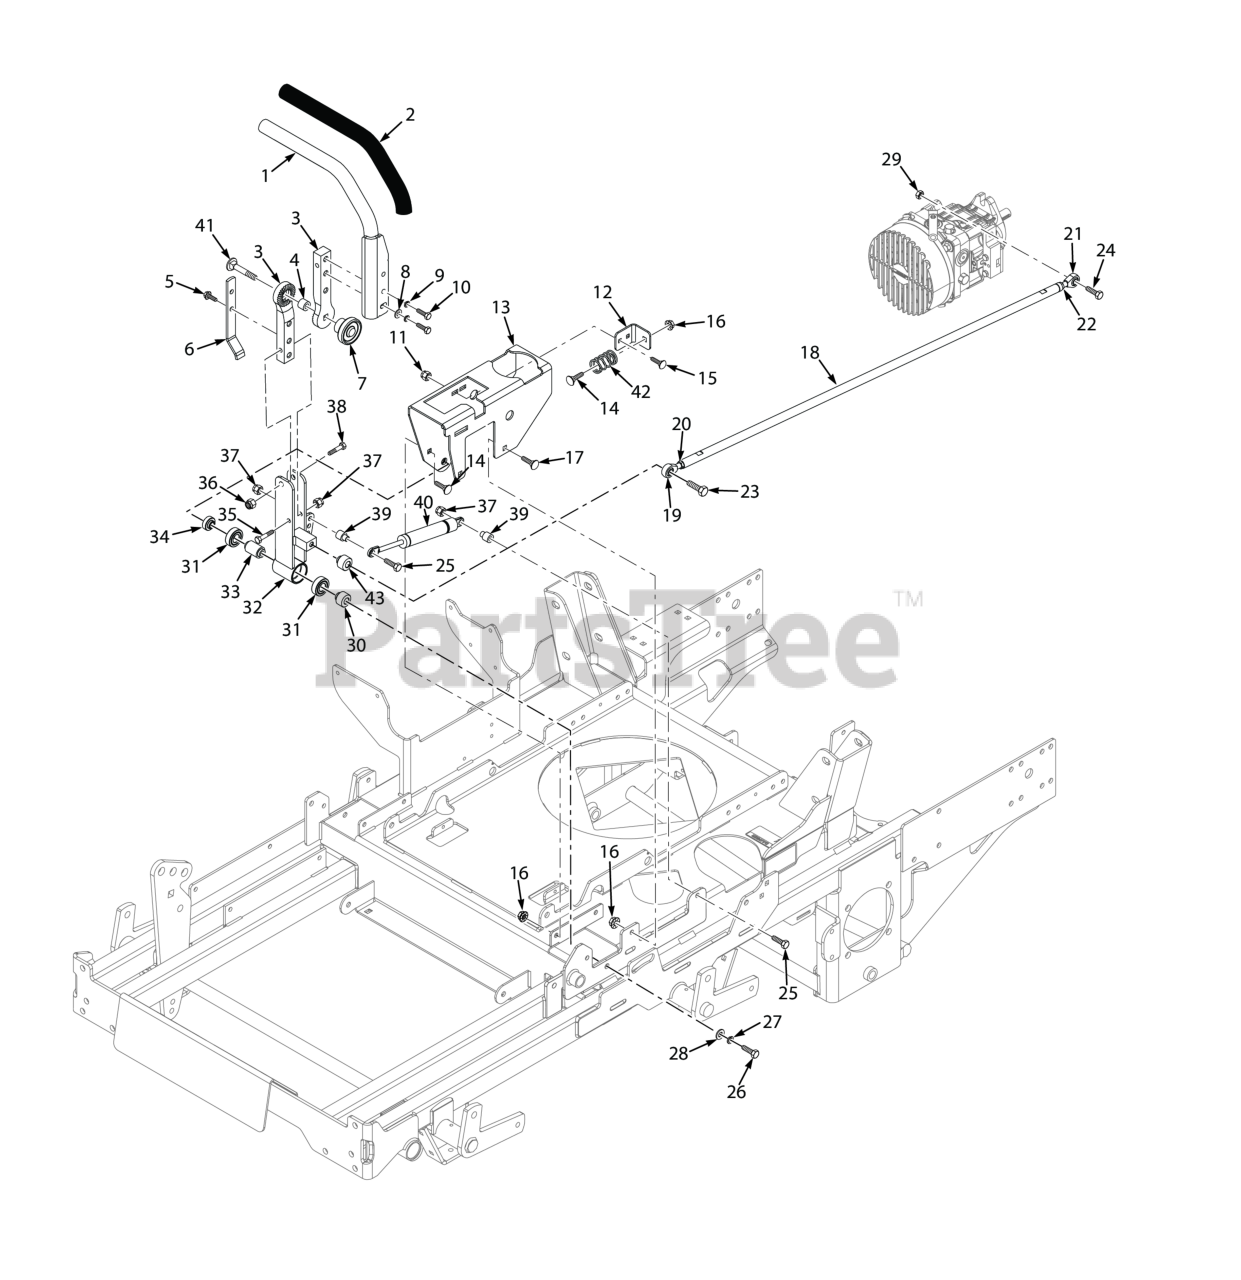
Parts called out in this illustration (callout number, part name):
1	Handle Bar w/Grip - LH
2	Grip, Control Handle
3	ADJUSTMENT ASSY, CNTL HANDLE
4	Spacer, Rubber
5	Capscrew, 5/16-18 x .75 Serrated Flange Hex Head
6	Actuator, Switch
7	Knob, Control Handle
8	Flatwasher, 5/16-.375 x .875 x .083 (35BV & 37BV-EFI)
9	Lockwasher, 5/16 (.317 x .586 x .078) Helical Spring
10	Bolt, Heax Head 5/16-18 x 1" (48V / 52V)
11	Nut, Flanged Elastic Stop 1/4-20
12	Mounting Bracket, Spring Return
13	Control Plate w/Decals LH
14	Bolt, 5/16-18 x .75 RHSN Carriage
15	Serr. Fl. Hex Head CPSCR, 1/4-20 x 3/4"
16	Nut, Serrated Flange 5/16-18 (Right Front Engine Mounting, Briggs and Kohler Only)
17	HHCS, 5/16-18 X .75 FLG
18	Linkage Assy., Pump Control (incl. #19 - #22)
19	Rod End, Male 3/8"-24 LH Thread
20	Nut, 3/8-24 UNF LH Jam
21	Rod End, Male - RH, 3/8-24 Thread
22	Nut, 3/8-24 UNF R.H. Thread
23	Bolt, Hex Head 3/8-16 x 1-3/4" (Kohler EFI)
24	Bolt, Hex Head 3/8-16 x 1-1/4", Kawasaki FX / FT & FT-EFI
25	Bolt, Hex Head 5/16-18 x 1-1/2" (Right Front Engine Mounting, Briggs and Kohler Only)
26	Bolt, Hex Head 3/8-16 x 4-1/4"
27	Lockwasher, 3/8" Spring, Kawasaki FX / FT & FT-EFI / B&S 32BV
28	Flatwasher, 3/8" Special (.391 x .938 x .105)
29	Bolt, Hex Head 3/8-16 x 1" Ser. Flg.
30	Spacer, Controls
31	BEARINGS, BALL, NEUTRAL RETURN
32	Control Lever Weldment, RH
33	Spacer, Bearing
34	Spacer, Controls
35	Bolt, Hex Head 5/16-18 x 2-1/2" (x3) (35BV & 37BV-EFI)
36	HEX NUT, ELASTIC STOP LOCK, 3/8-16
37	HEX NUT, ELASTIC STOP LOCK, 5/16-18
38	Capscrew, Hex Head 3/8-16 x 2.0"
39	Spacer, Pump Dampener
40	Gas Damper
41	Bolt, RDHD Carr. 3/8-16 x 1-1/2 (52" & 61")
42	Return Spring, Control Arm
43	SPACER
